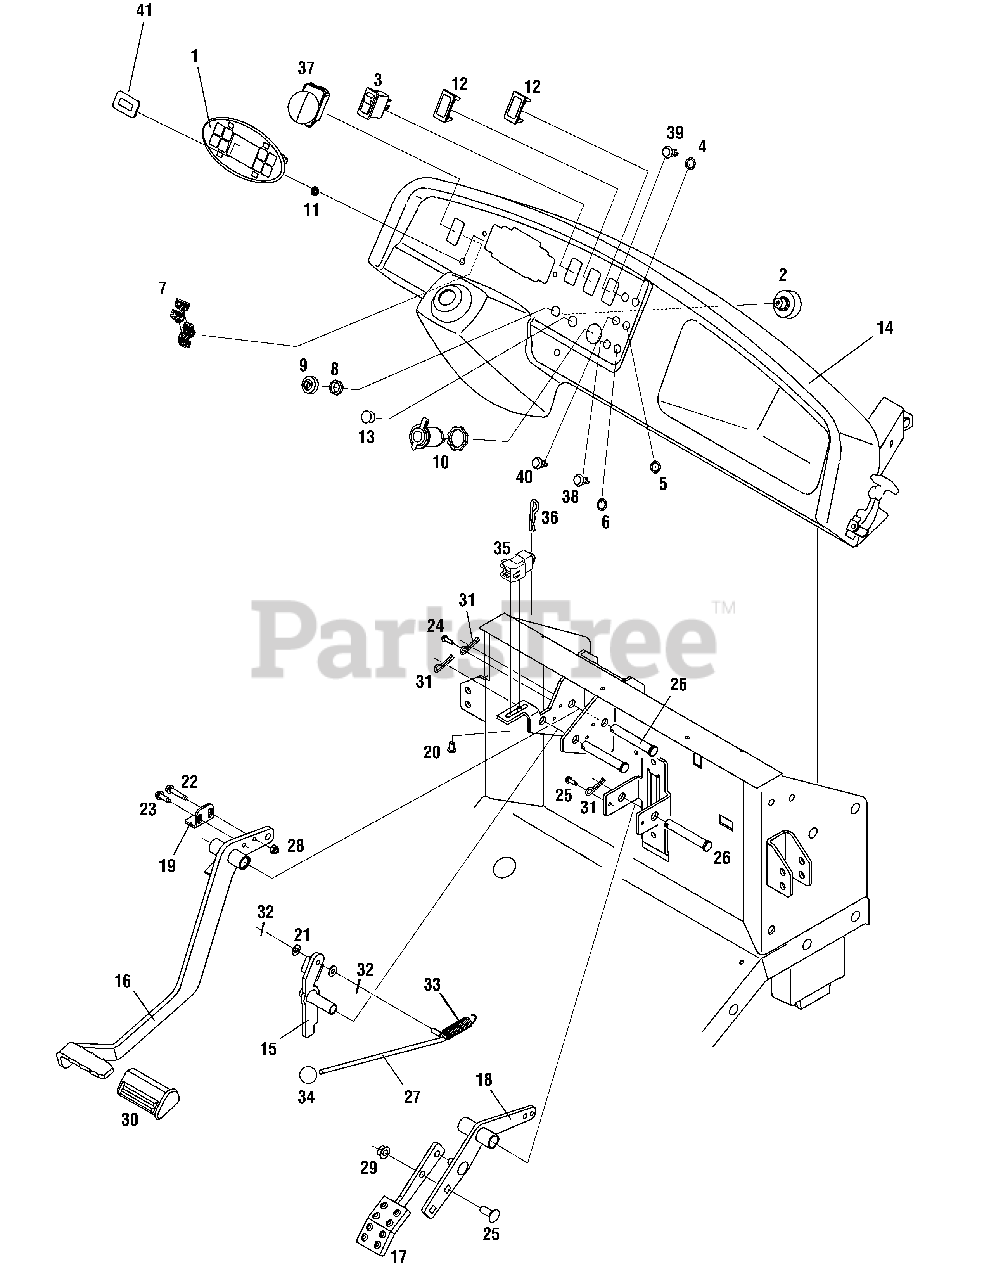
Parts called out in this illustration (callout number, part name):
1	Instrument Dash Cover (4 warning lights)
2	Switch, Key
3	Rocker Switch
4	Switch, Green
5	Switch, Yellow
6	Switch, Red
7	Accessory Harness, Diff Lock
8	Nut, Ignition Switch, 5/8-32
9	Cap, Ignition Switch
10	Power Receptacle, 12V
11	Nut, Retainer, 1/8
13	Plug, Horn Switch
14	Dash Panel Kohler
15	Lever , Parking Brake
16	Pedal Assembly, Brake
17	Pedal Assembly, Throttle
18	Pedal Arm Assembly, Throttle
19	Plate, Brake Switch
20	Screw, Hi-Lo, 1/4-20 x .5
21	Washer, Flat .25 x .630 x .0515
22	Screw, Self-Tapping, 1/4-20x1.25
23	Screw, Self-tapping, 1/4-20, .75
24	Screw, Self-tapping, #10-32 x .625
25	Bolt, Carriage, 3/8-16 x 1.0
26	Pin, Clevis .50 x 3.25
27	Rod, Brake Lock
28	Nut, Hexlock, 1/4-20 GR 8
29	Nut, Flange Lock, 3/8-16
30	Pad, Brake Pedal
31	Pin, Cotter, 5/32 x 1.0
32	Pin, Cotter, 1/16
33	Spring, Extension, .637 x 2.972
34	Knob, Ball
35	Snap Mount Switch, Interlock
36	Pin, Cotter.08 x 1.42
37	Differential Lock Switch
38	Red LED Indicator Light
39	Green LED Indicator Light
40	Yellow LED Indicator Light
41	Hour Meter Indicator
